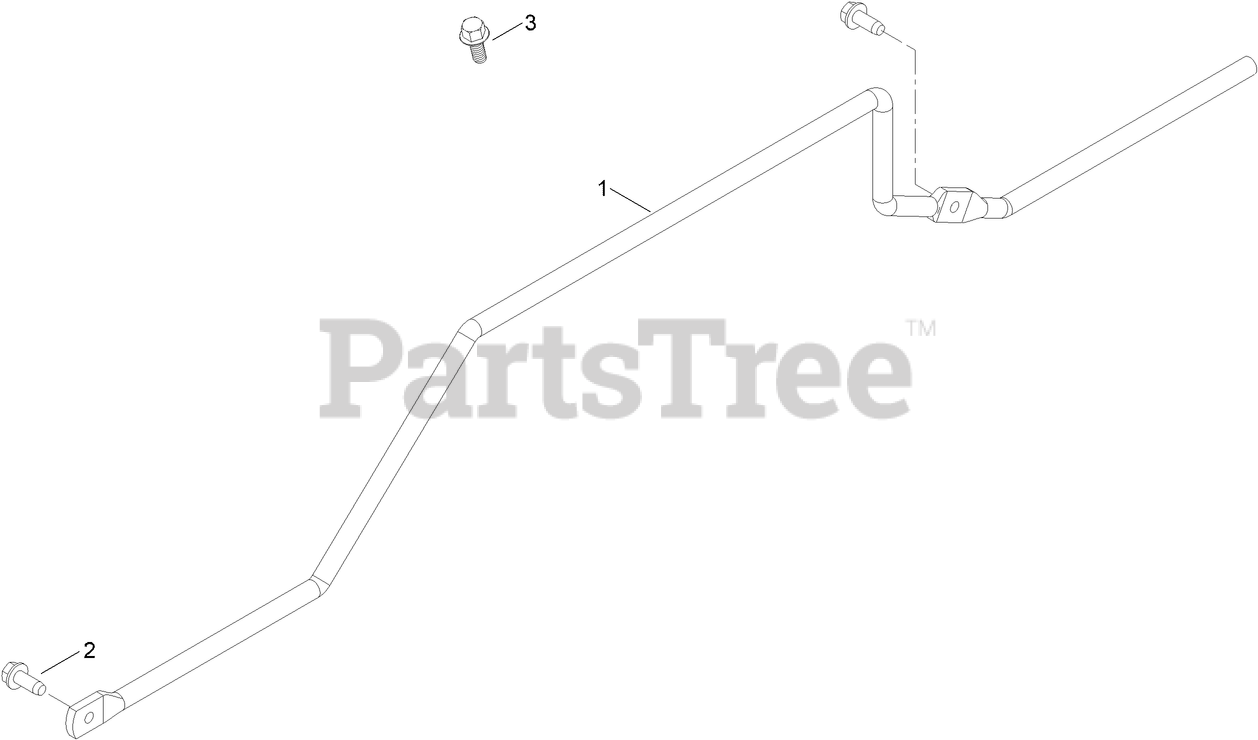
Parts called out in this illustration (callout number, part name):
1	ROD-FRENCH GUARD
2	SCREW-HWH
3	SCREW-HHF
